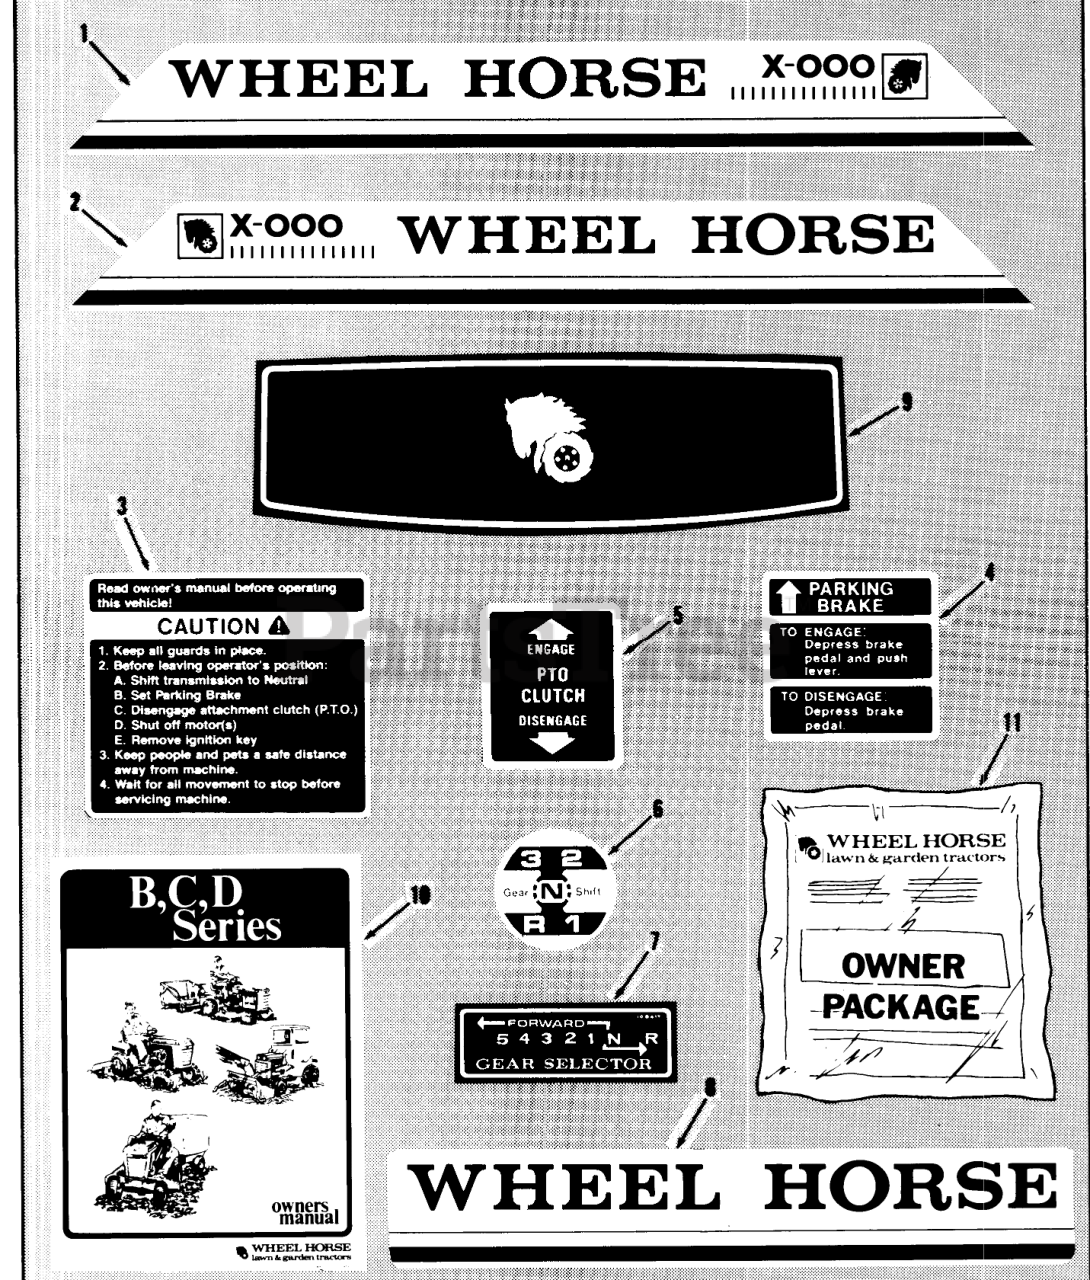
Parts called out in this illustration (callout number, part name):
1	Decal-Hood RH B-82
1	Decal-Hood RH B-112
1	Decal-Hood RH B-115
1	Decal-Hood RH B-165
2	Decal-Hood LH B-82
2	DECAL-HOOD B-112 LH
2	DECAL-HOOD B115 LH
2	Decal-Hood LH B-165
3	DECAL-CAUTION
4	Decal Parking Brake
5	DECAL-PTO CLUTCH
6	DECAL-SHIFT
7	DECAL-SHIFT
8	Decal-Rear
9	Decal-Hood
10	Owner-s Manual
11	New Tractor Loose Parts Package B-112 Only
11	New Tractor Loose Parts Package B-82 Only
11	New Tractor Loose Parts Package B-115 Only
11	New Tractor Loose Parts Package B-165 Only
